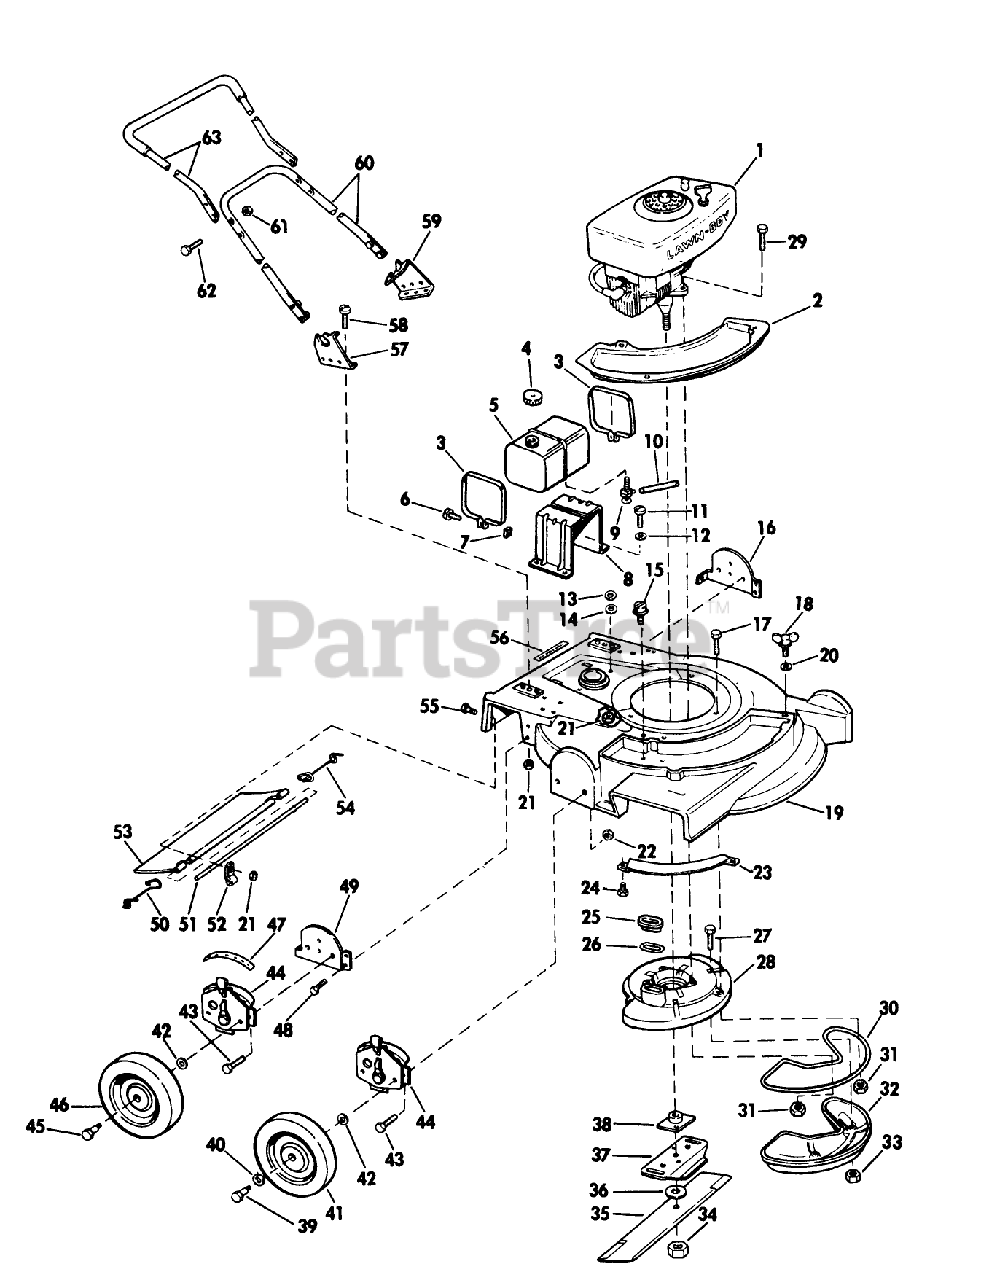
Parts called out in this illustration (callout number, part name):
7	Nut
9	VALVE&SCREEN SM
11	BOLT PIONEER
14	WASHER
17	SCREW
18	WING SCREW LAWRE
22	NUT
23	BAR-TOE
25	SLEEVE
26	GASKET S
31	NUT-LOCK F
34	NUT-BLADE
36	WASHER
38	PLATE AND COLLAR ASM
39	BOLT WHEEL
40	Washer
42	WASHER WROUGHT
45	BOLT-SHOULDER
50	SPRING;TRAILING SHIELD RH
51	ROD 21" ADVANCE
52	CLAMP ROD KMC
54	SPRIG T/SHLD ASOC
58	BOLT RB&W
61	STOP NUT
